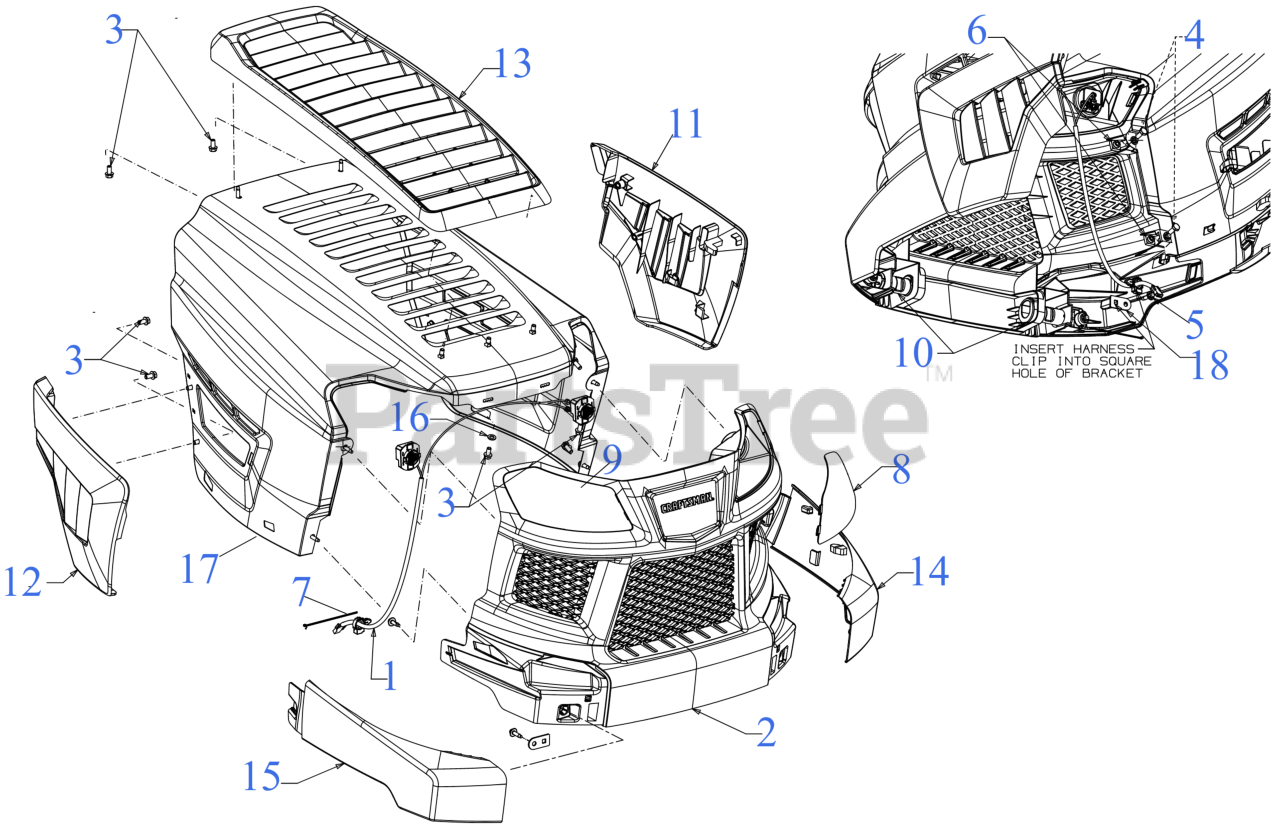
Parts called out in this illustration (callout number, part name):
1	HEADLIGHT LED HARNESS
2	GRILLE
3	HEX SCREW 1/4-15 x .50
4	SCREW 1/4-20 x .62 SPEC GR5
5	SCREW 1/4-10 x .750
6	SQUARE NUT 1/4-20
7	CABLE TIE
8	GRILLE LENS (LH)
9	GRILLE LENS (RH)
10	HOOD PIVOT PIN
11	HOOD SIDE COVER (LH)
12	HOOD SIDE COVER (RH)
13	HOOD SCOOP
14	GRILLE PANEL (LH) (LIBERTY RED)
15	GRILLE PANEL (RH) (LIBERTY RED)
16	FLAT WASHER .281 x .50 x .063
18	HARNESS CLIP BRACKET
